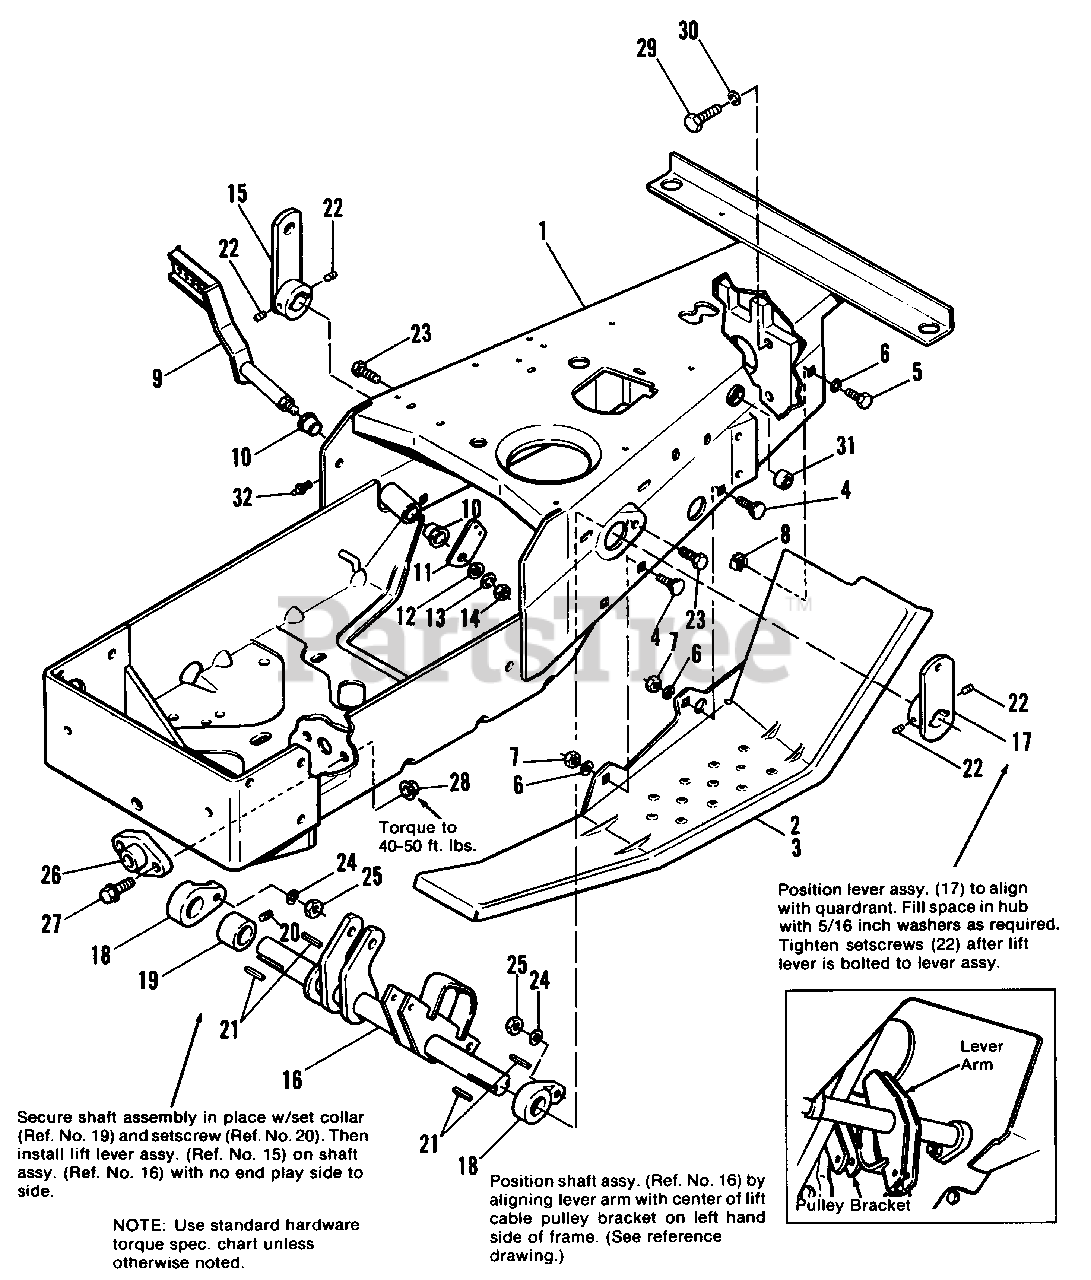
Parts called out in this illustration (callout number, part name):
1	FRAME & BUSHING ASSY. (7117 Only)
2	FOOTREST, R.H.
3	FOOTREST, L.H.
4	BOLT, Carriage, 5/16-18 x 3/4
5	CAPSCREW, Hex Hd., 5/16-18 x 3/4
6	LOCKWASHER, 5/16
7	NUT, Hex, Full, 5/16-18
8	NUT, Speed, Tinnerman, 5/16-18
9	FOOT PEDAL ASSY.
11	ARM, Pedal Foot
12	WASHER, 3/8
13	LOCKWASHER, 3/8
14	NUT, Hex, Full, 3/8-16
15	FRONT LIFT LEVER ASSY. (R.H.)
16	LIFT SHAFT ASSY.
17	LIFT LEVER ASSY. (L.H.)
18	BEARING, Lift Lever
19	COLLAR, Set
20	SETSCREW, Cup Pt., 5/16-18 x 3/8
22	SETSCREW, Skt. Hd., 5/16-18 x 1/4
23	CAPSCREW, Hex Hd., 5/16-18 x 1-1/4
24	LOCKWASHER, 5/16
25	NUT, Hex, Full, 5/16-18
26	BEARING, Pivot
27	CAPSCREW, Whiz, 3/8-16 x 1-1/4
28	LOCKNUT, Hex, Flange, Whiz, 3/8-16
29	CAPSCREW, Hex Hd., 7/16-14 x 1-1/2
30	LOCKWASHER, 7/16
32	FRAME & BUSHING ASSY. (7112 & 7116 Only)
32	FITTING, Lube
